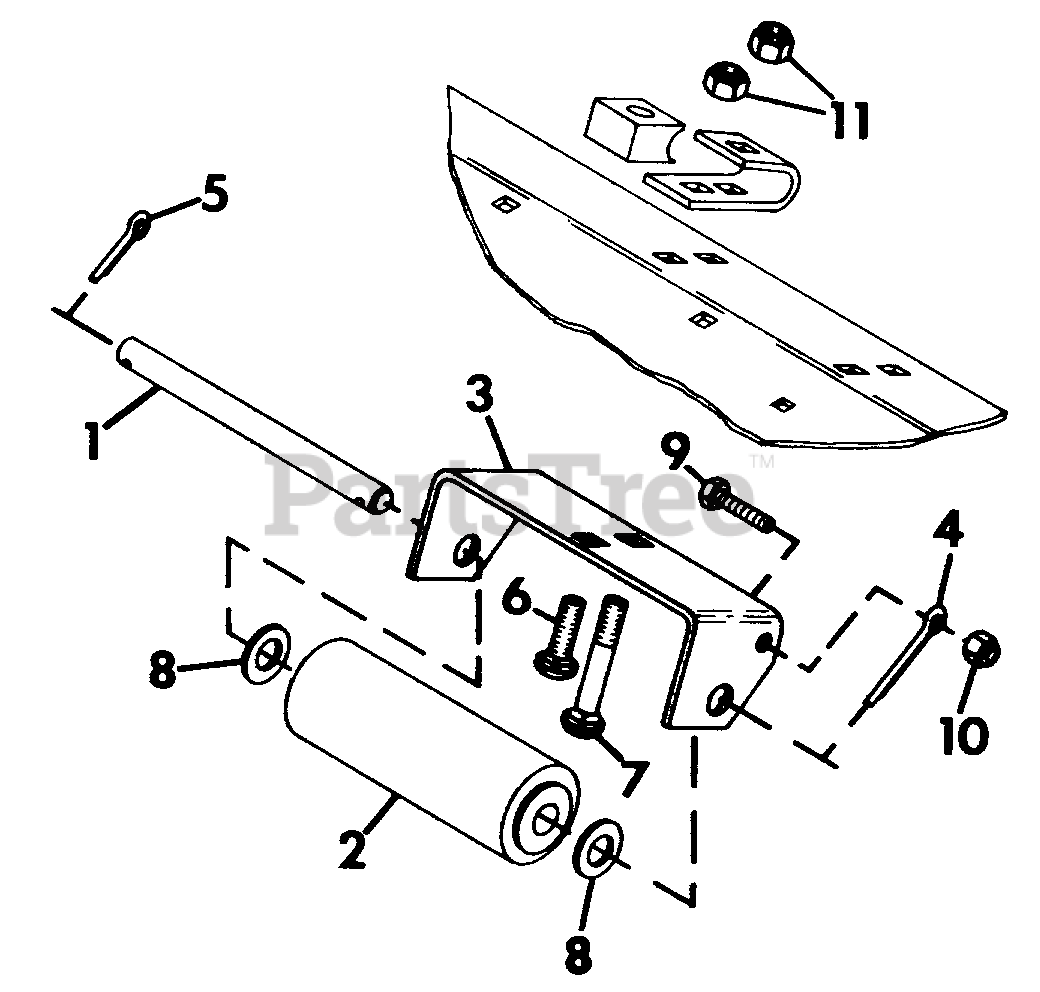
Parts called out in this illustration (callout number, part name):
1	SHAFT, CENTER ROLLER
2	ROLLER, GAUGE
3	BRACKET, REAR ROLLER
4	PIN, COTTER .25X2.00
5	PIN, COTTER .25X1.00
6	BOLT, 3/8-16X1.25 RD HD SQ NK
7	BOLT, 3/8-16X2.25 RD HD SQ NK
8	WASHER, FLAT .656X1.312X.095
9	BOLT, HEX 1/4-20X.75
10	NUT, LOCK 1/4-20
11	NUT, LOCK 3/8-16
